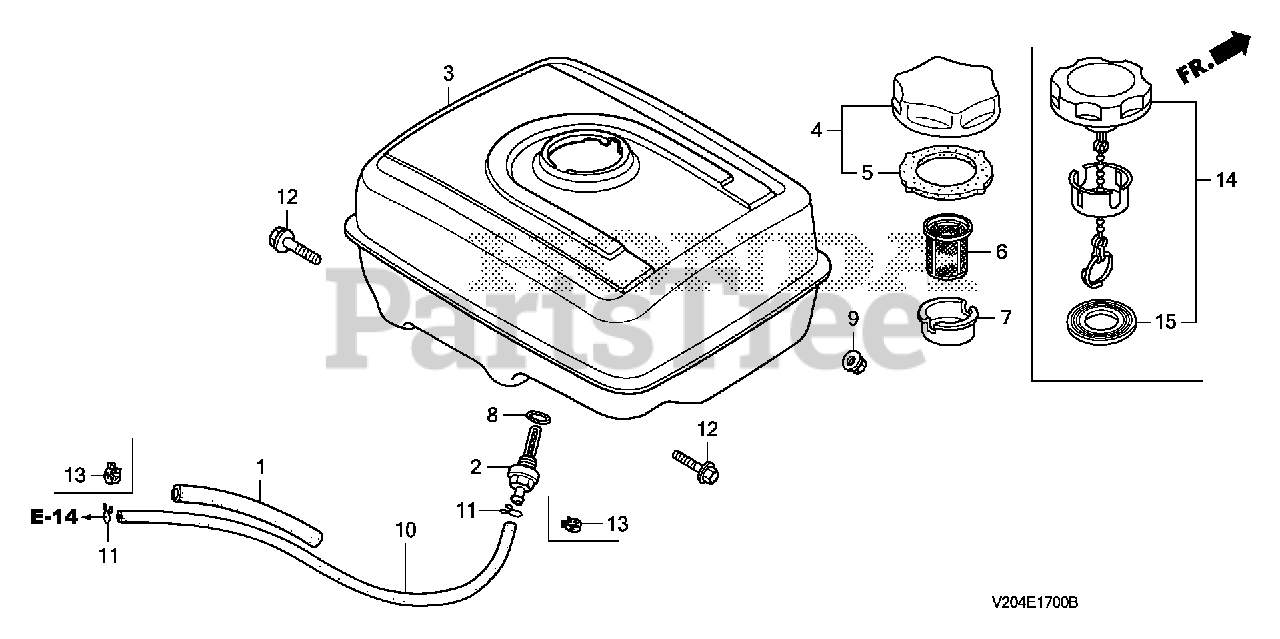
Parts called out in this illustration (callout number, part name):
1	RUBBER, SUPPORTER (107MM)
2	JOINT, FUEL TANK
3	TANK, FUEL *NH31* (MCKINLEY WHITE)
3	TANK, FUEL *R280* (POWER RED)
6	FILTER, FUEL
8	O-RING (13.5X1.5) (ARAI)
8	O-RING (14MM) (NOK)
9	NUT, FLANGE (8MM)
10	TUBE, FUEL (4.5X210) (FKM)
12	BOLT, FLANGE (8X25)
13	CLAMP, TUBE (D8)
14	CAP, FUEL FILLER
15	GASKET, FUEL FILLER CAP (39X62X3) (RADICON)
